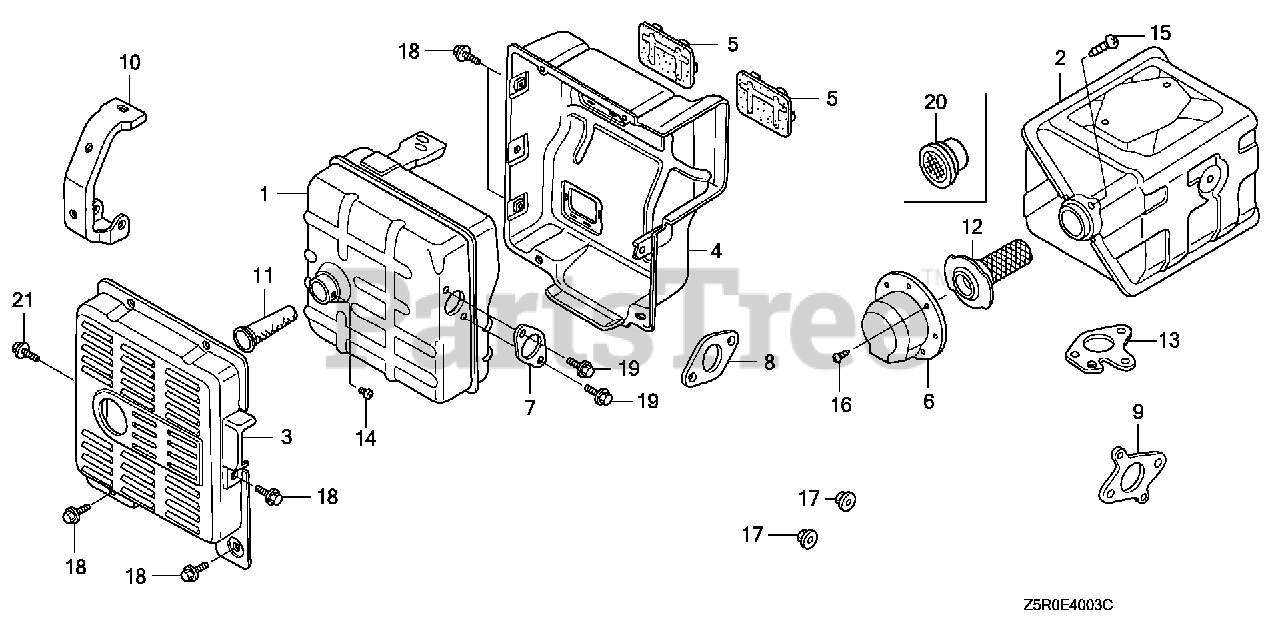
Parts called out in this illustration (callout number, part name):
1	MUFFLER (TSURUMI)
3	PROTECTOR, MUFFLER (OUTER)
4	PROTECTOR, MUFFLER (INNER)
5	SEAL, MUFFLER PROTECTOR
7	GASKET, EX. PIPE
15	SCREW, TAPPING (4X6)
17	NUT, FLANGE (8MM)
18	BOLT, FLANGE (6X12)
19	BOLT, FLANGE (8X20)
20	NETTING, WIRE FLANGE
21	BOLT, FLANGE (6X12)
